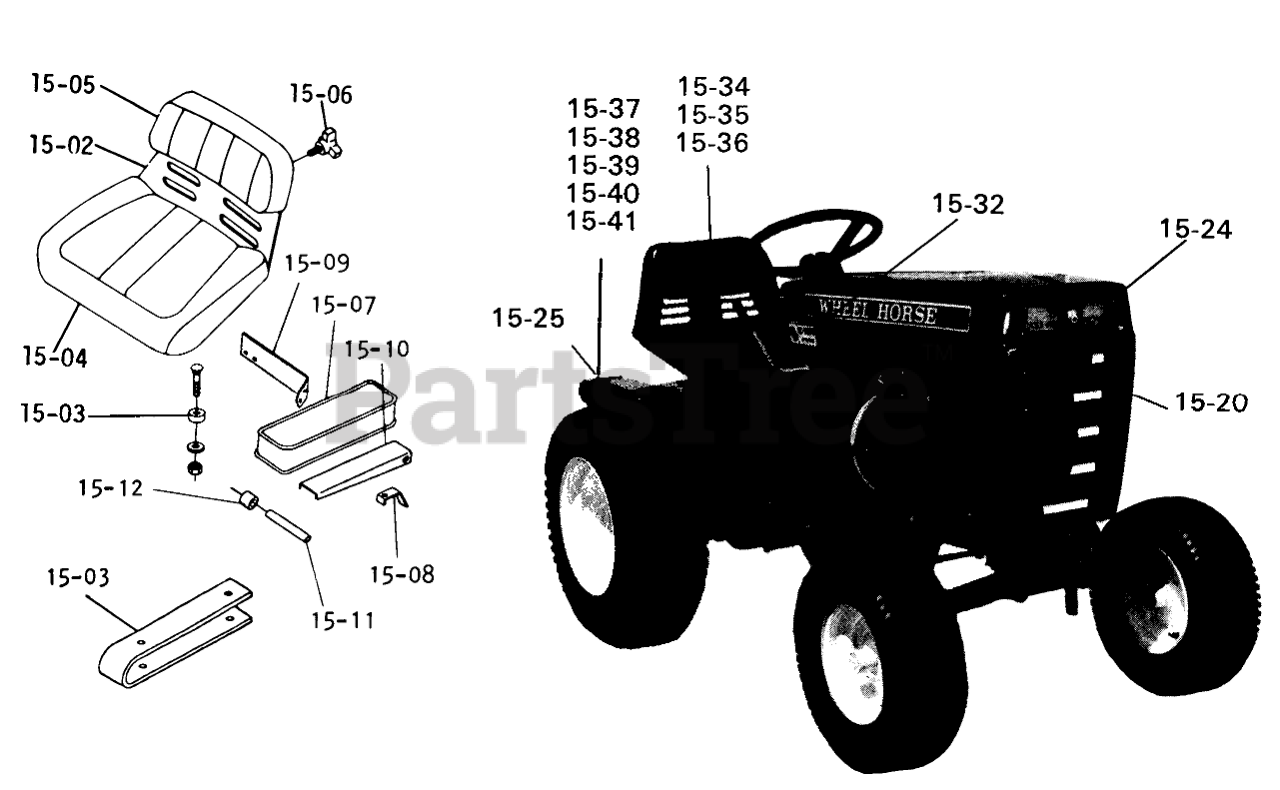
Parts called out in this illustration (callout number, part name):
15-02	Seat Base
15-03	Spring
15-03	Nut
15-04	Seat Cushion
15-04	Screw
15-05	Back Cushion
15-06	Bolt
15-06	Lockwasher
15-06	Knob 8 HP
15-07	Arm Rest Pad
15-08	Arm Stop
15-09	Bracket-R.H.
15-09	Bracket-L.H.
15-10	Arm
15-10	Bolt-Carriage
15-10	Nut
15-10	Screw-Hex. Hd.
15-11	PIN-SPLIT ROLLED
15-12	SPACER
15-12	NUT
15-12	Lockwasher
15-12	Bolt
15-12	Washer
15-20	Decal
15-23	DECAL-WHEEL HORSE
15-23	Decal
15-23	DECAL C 160
15-37	Lockwasher
15-38	Decal-Maintenance
15-39	Decal-Read Manual
15-41	DECAL PTO SPD. CONT
15-42	DECAL-HAND LIFT
15-42	Washer
15-42	Washer 13/32
15-42	Decal-Tach-a-matic
15-42	Decal
